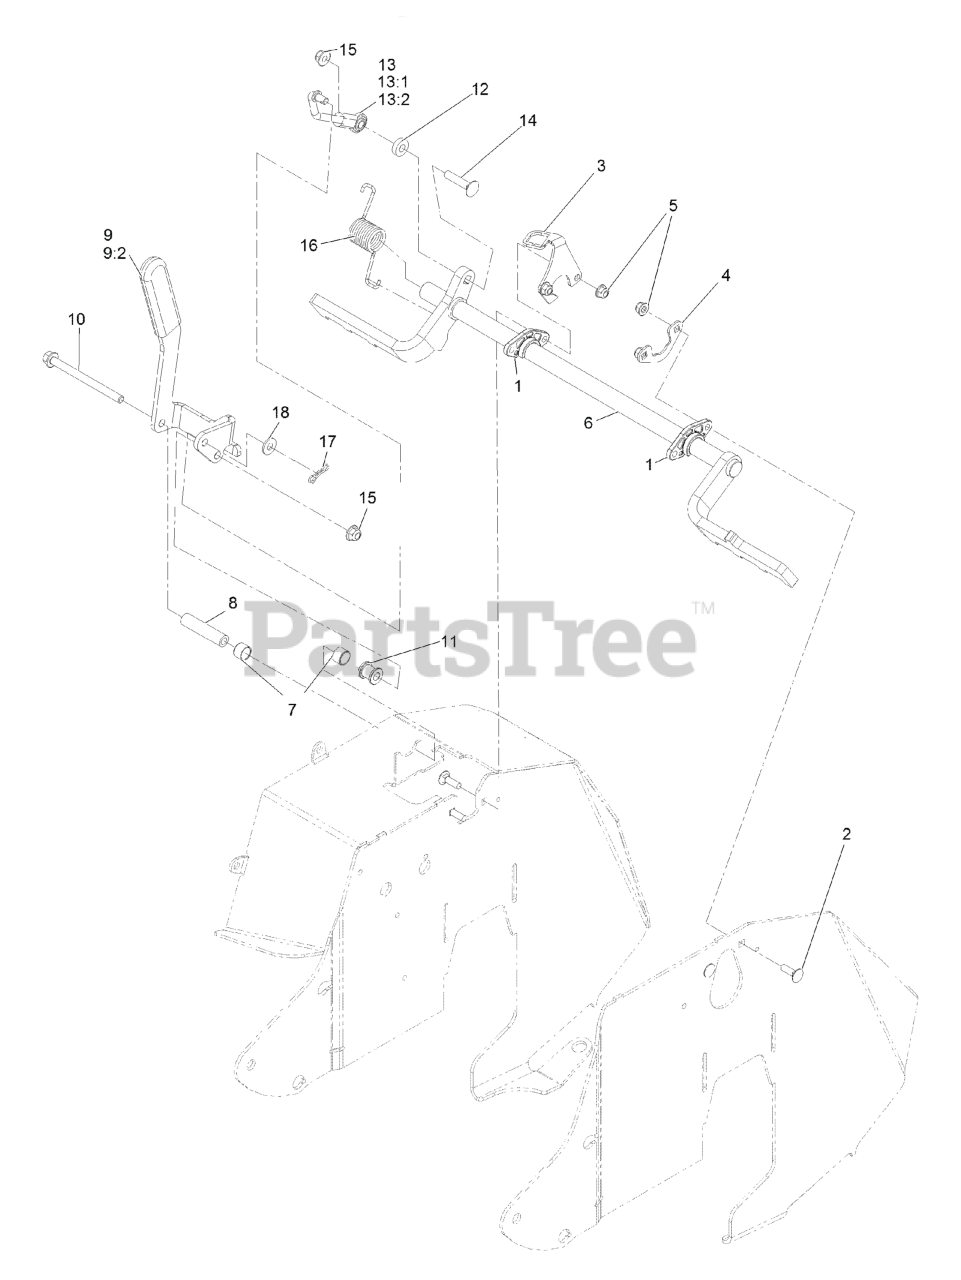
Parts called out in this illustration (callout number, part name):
1	BUSHING-FLANGE
2	BOLT-CARR
3	BRACKET-SWITCH
4	SUPPORT, BEARING
5	NUT-HF, NI
6	WLD-BRAKE SHAFT 32/36
7	SLEEVE-BUSHING
8	BUSHING-PIVOT
9	ASM-BRAKE LEVER WITH GRIP
9:2	GRIP-LEVER
10	SCREW-HF
11	SPACER-.39IDX.88ODX.88L
12	SPACER
13	ASM-BRAKE LINK
13:1	JOINT-BALL, END
13:2	ROD-BRAKE
14	SCREW-CARR
15	NUT-HF, NI
16	SPRING-TORSION
17	PIN-COTTER, LOCKING
18	WASHER-FLAT
